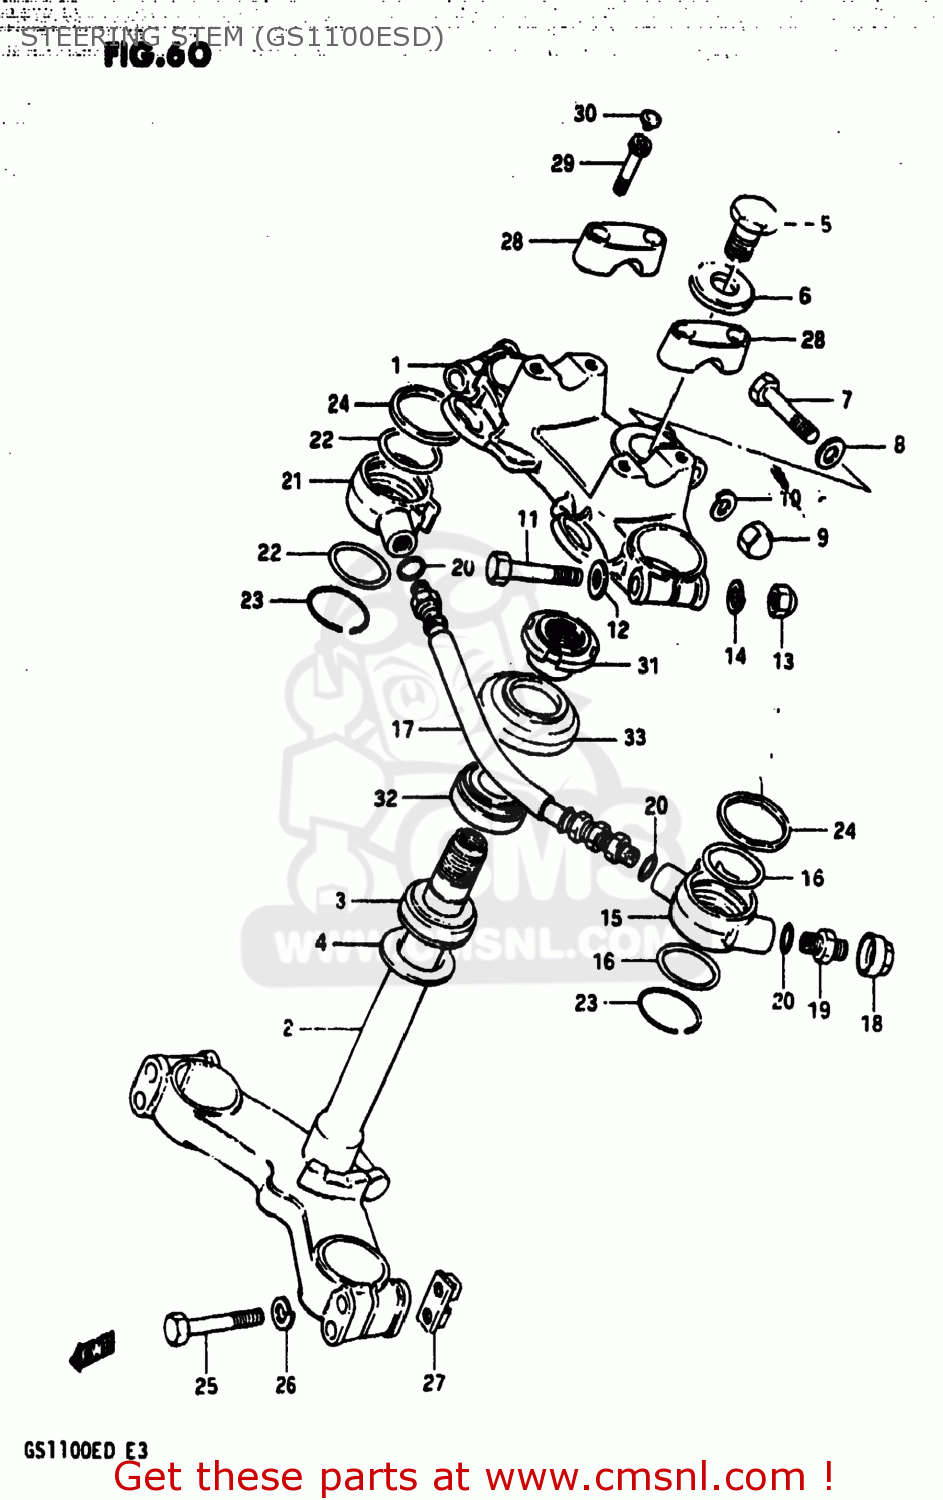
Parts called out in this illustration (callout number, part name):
1	HEAD,STEERING STEM
2	STEM,STEERING
3	BEARING
4	WASHER,THRUST
5	SUZUKI
6	SUZUKI
7	BOLT
8	WASHER
9	NUT,M8X1.25X12
10	LOCK WASHER
11	BOLT 10X55
12	WASHER 10MM
13	NUT 10MM
14	LOCK WASHER
15	JOINT,AIR,LEFT
16	O RING
17	JOINT,AIR TUBE
18	CAP,VALVE
19	VALVE,FRONT FORK AIR
20	O-RING
21	JOINT,AIR,RIGHT
22	O RING
23	SNAP RING
24	CUSHION,HEADLAMP BRACKET
25	BOLT 8X55
26	LOCK WASHER
27	NUT,FR FORK INNER TUBE
28	HOLDER,HANDLEBAR
29	BOLT
30	CAP(OD:14.5)
31	NUT,STEERING STEM
32	TAPER,ROLLER BEARING
33	DUST SEAL,STEERING UPR
